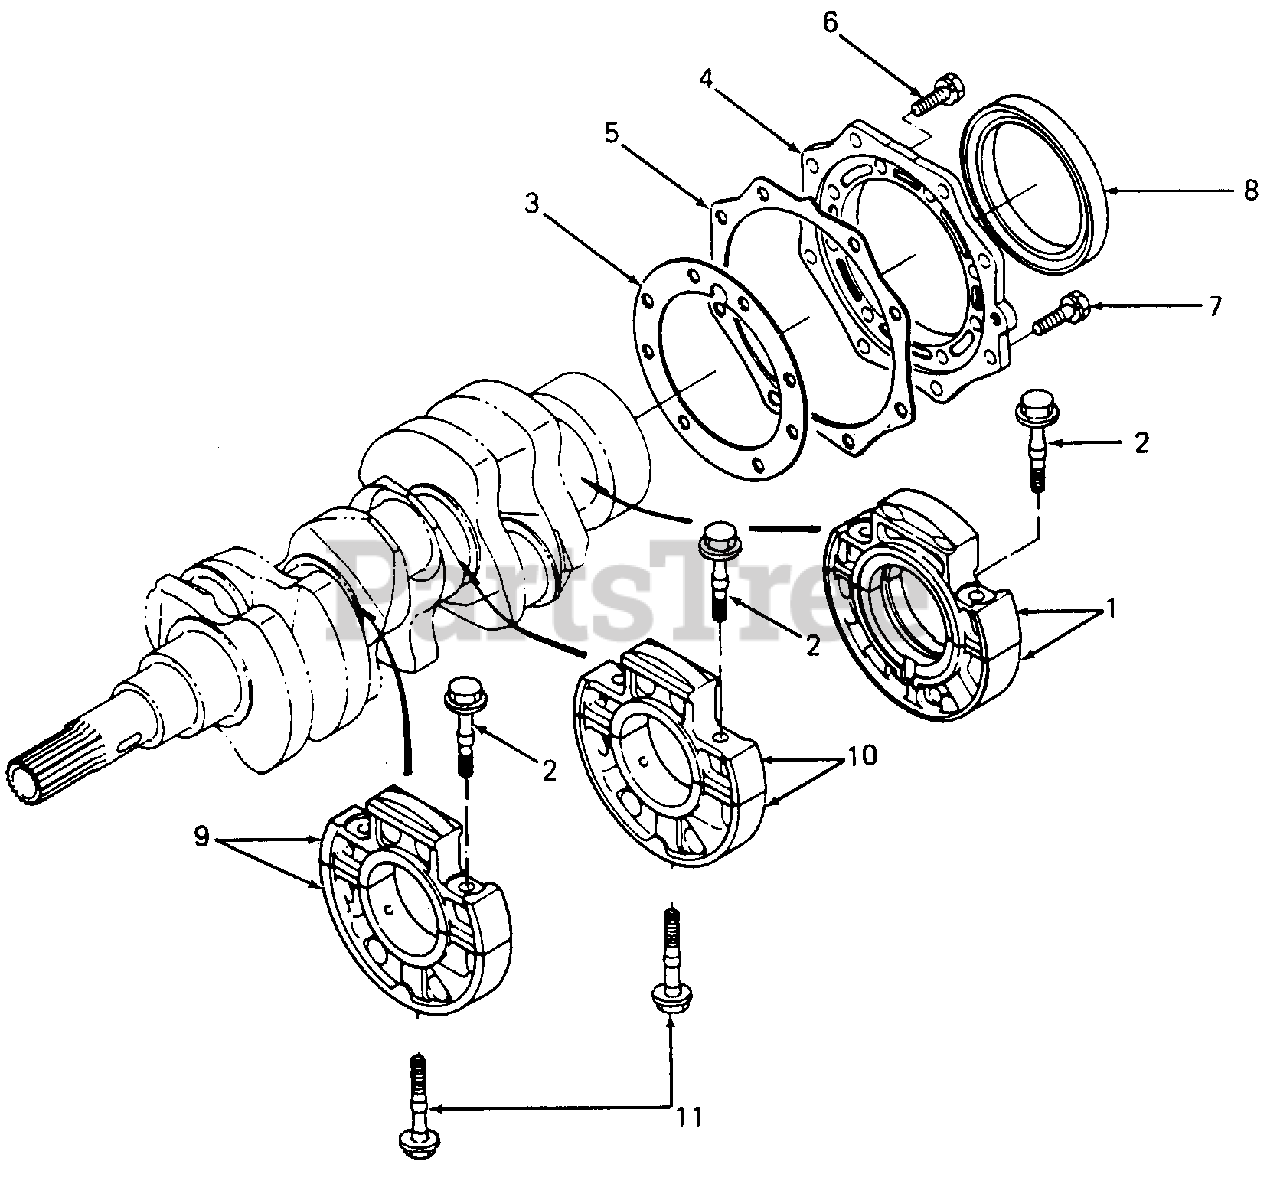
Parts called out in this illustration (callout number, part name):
1	Case, Main Bearing
2	Bolt, Bearing Case
3	Shim, Bearing Case
4	Cover, Bearing Case
5	Gasket, Bearing Case
6	Screw, Hex Cap w/Washer
7	Screw, Hex Cap
9	Case, Main Bearing - 1
10	Case, Main Bearing - 2
11	Bolt, Bearing Case
